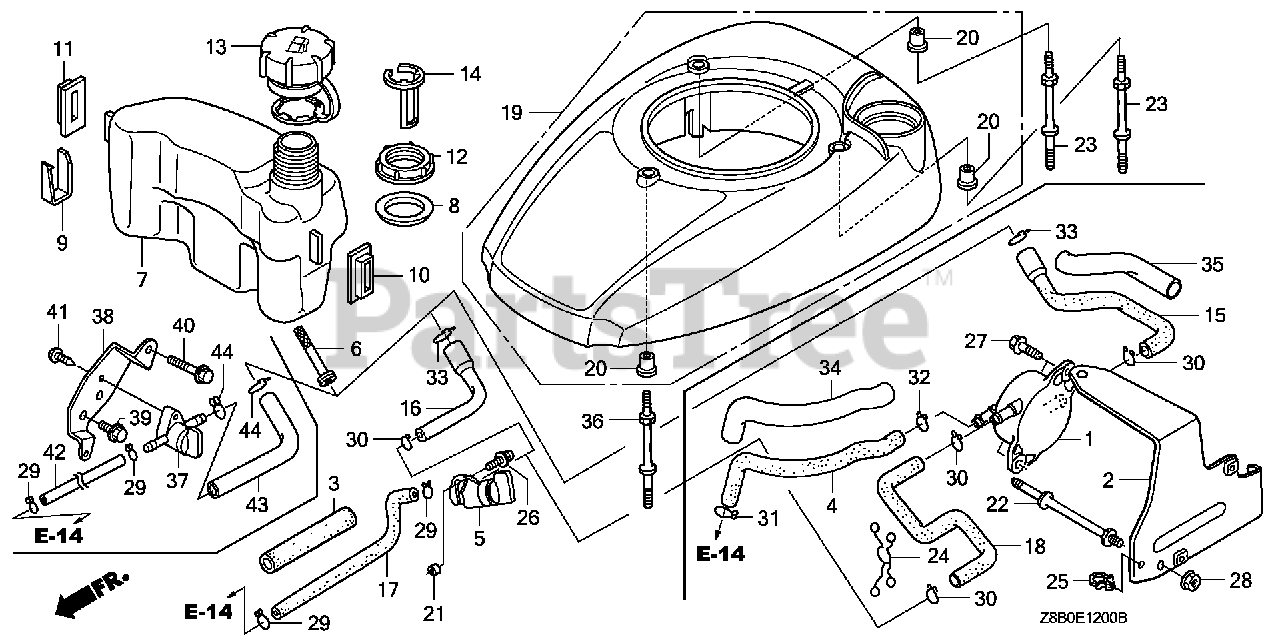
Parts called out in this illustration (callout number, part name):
3	RUBBER, SUPPORTER (107MM)
5	PETCOCK ASSY.
6	FILTER, FUEL
7	TANK, FUEL
8	SEAL, FUEL FILLER NECK
9	CLIP, TANK MOUNTING
10	RUBBER A, TANK MOUNTING
11	RUBBER B, TANK MOUNTING
12	NUT, TANK MOUNTING
13	CAP ASSY., FUEL TANK
14	GAUGE, FUEL LEVEL
16	TUBE, FUEL TANK
17	TUBE, FUEL
19	COVER, FAN *NH1* (BLACK) (NOT AVAILABLE)
19	COVER, FAN *R280* (POWER RED) (NOT AVAILABLE)
20	COLLAR, FAN COVER
21	COLLAR, FUEL PETCOCK
23	BOLT, STUD (H=42.5MM)
26	SCREW-WASHER (5X10)
29	CLIP, TUBE (B8)
30	CLIP, TUBE (B10)
33	CLIP, TUBE (C11)
36	BOLT, STUD (H=42.5MM)
